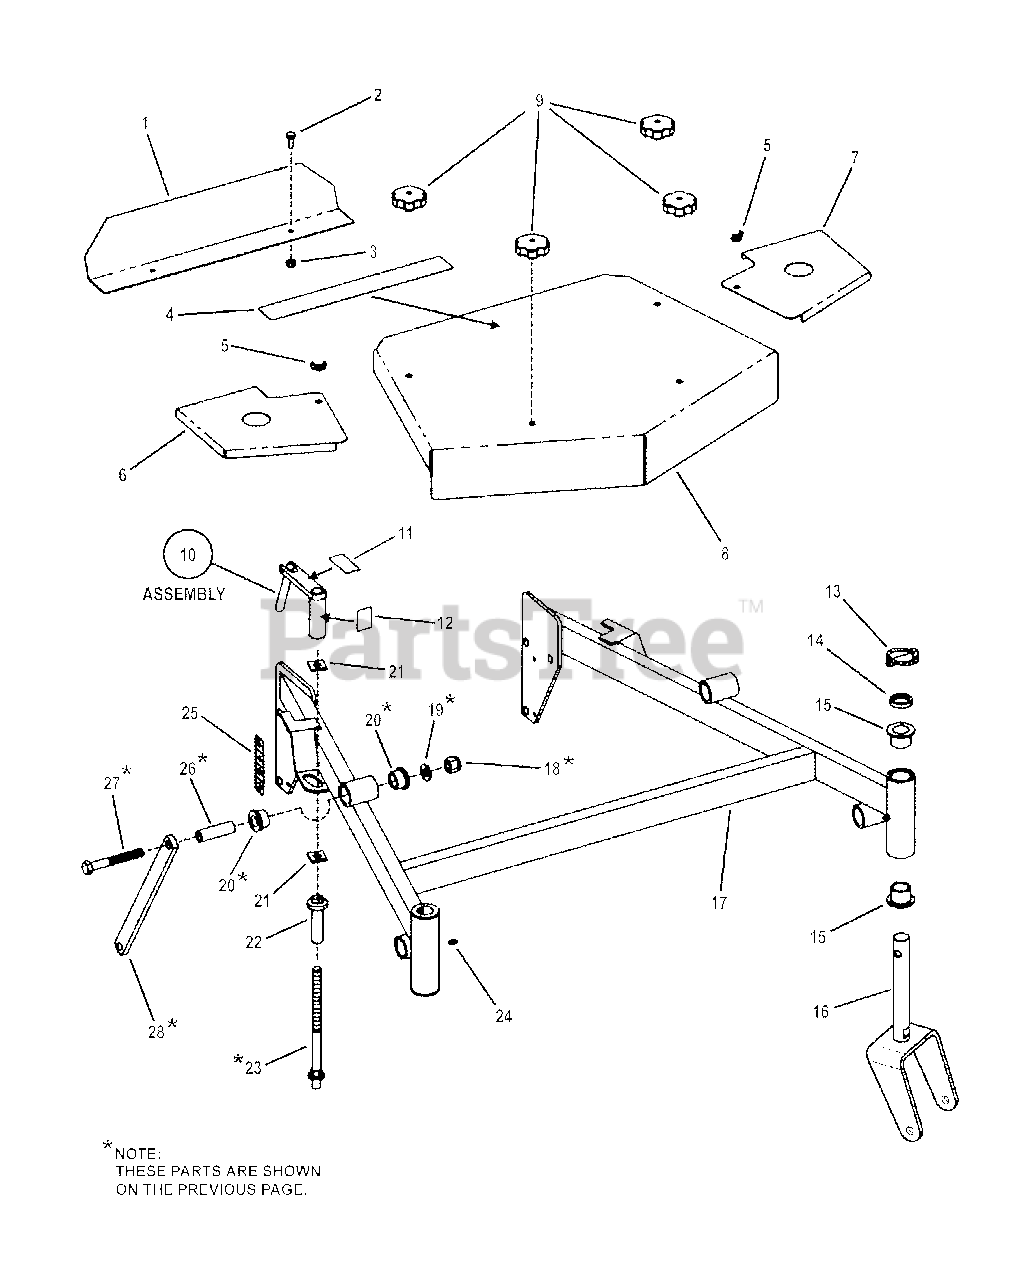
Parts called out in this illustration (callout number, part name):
1	SHIELD, Muffler (SPA611)
2	BOLT, 5/16-18 X 3/4 GD5
3	NUT, 5/16-18 HEX NYLON LOCK
4	*DECAL, SNAPPER Pro w/Trademark
4	*DECAL, Snapper Pro (silver, 16-1/2" long)
5	WING NUT, 5/16-18
6	COVER, 48" Right
6	COVER, 52" Right
6	COVER, 61" Right
7	COVER, 48" Left
7	COVER, 52" Left
7	COVER, 61" Left
8	COVER, 48" Center
8	COVER, 52" Center
8	COVER, 61" Center
9	KNOB, Hood (5/16-18 thread)
10	ASSEMBLY, Crank
11	*DECAL, Caution Handle May Be Hot (Adjustable Decks only)
12	*DECAL, Oil Threads Here (Adjustable Decks only)
13	LYNCH PIN, 7/16" Heavy Duty
14	SPACER, Powdered Metal
15	BUSHING
16	YOKE, Caster Weldment
17	WELDMENT, 48" Deck Frame (shown)
18	NUT, 1/2-13 HEX NYLON LOCK
19	WASHER, 1/2" Flat
20	BUSHING, Suspension
21	WASHER, Lift
22	LIFT WASHER (Weldment)
23	STUD, Lift, 1/2-13 Thread, Both Ends
24	FITTING, Straight Lube (for 3/16" drill)
25	*DECAL, Height of Cut
26	SLEEVE, Suspension
27	BOLT, 1/2-13 x 3-3/4" Hex Head, GR 5
28	ARM, Suspension, 12" Long
28	ARM, Suspension, 13-1/2" Long
